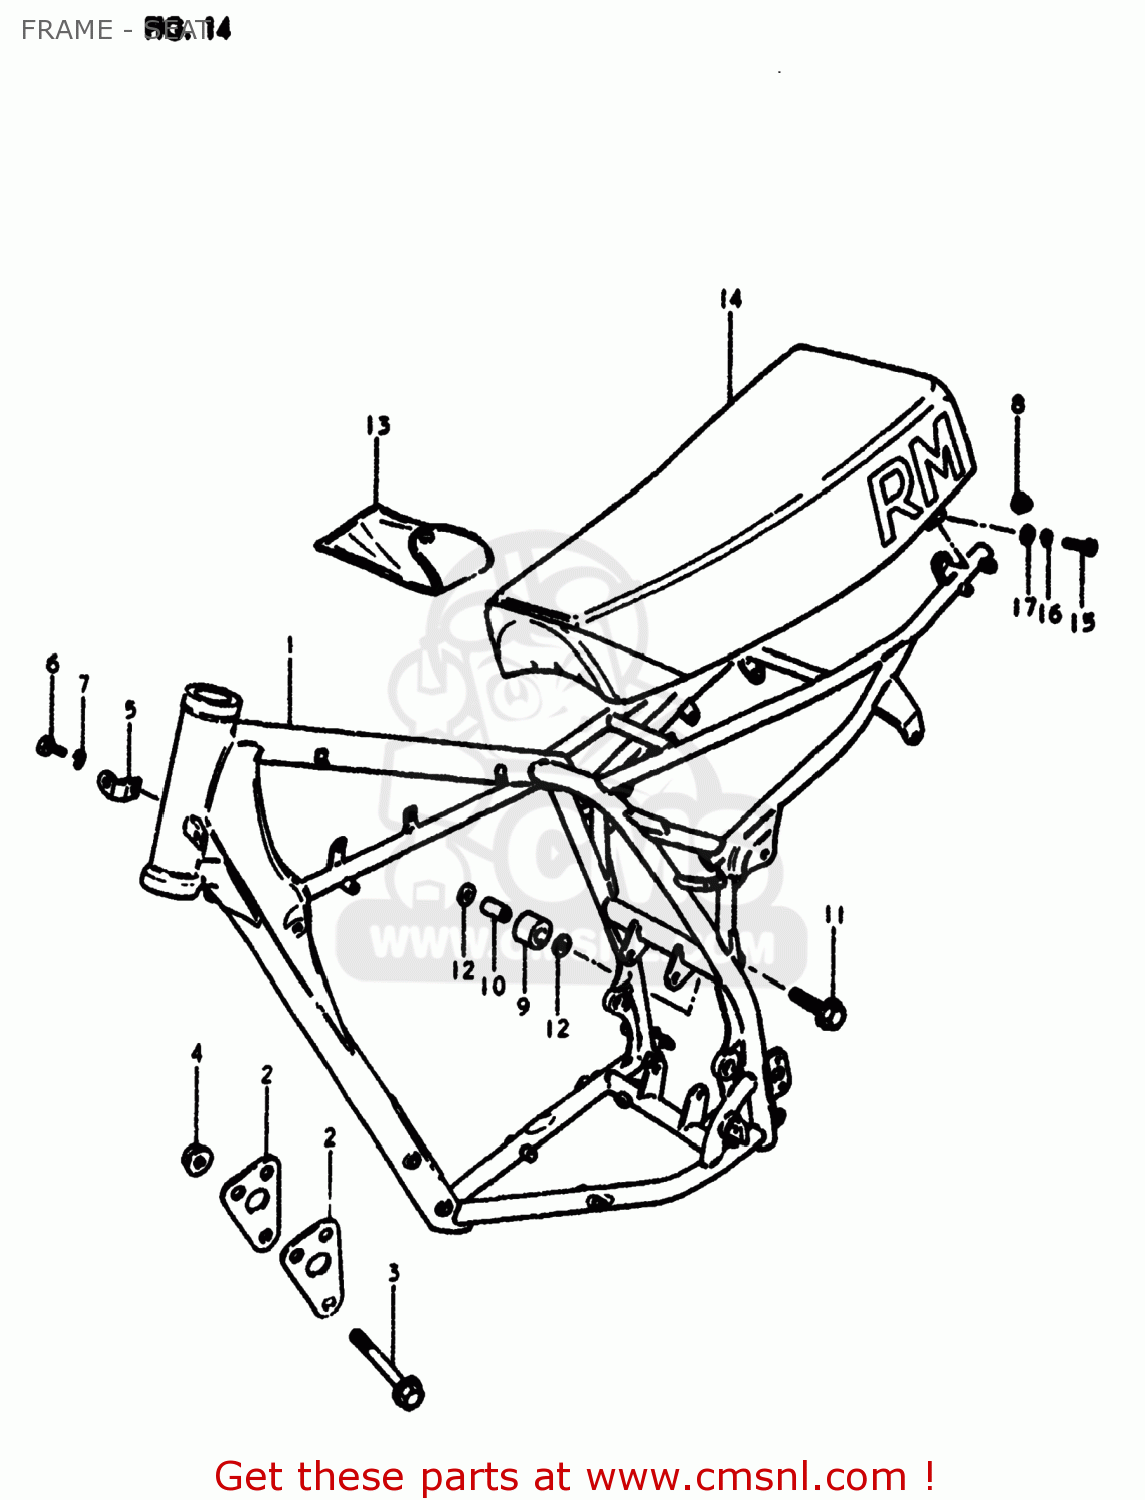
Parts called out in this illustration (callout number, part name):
1	FRAME
2	PLATE,ENGINE MOUNTING
3	BOLT(8X67)
4	NUT
5	PLATE,ENGINE MOUNTING
6	BOLT
7	LOCK WASHER
8	PLUG(OD:19)
9	ROLLER,CHAIN CONTROL
10	SPACER,CHAIN LENGTH ROLLER
11	BOLT(8X45)
12	WASHER
13	TOOL SET
14	SEAT ASSEMBLY
15	BOLT
16	LOCK WASHER
17	WASHER(6.5X18X1)
